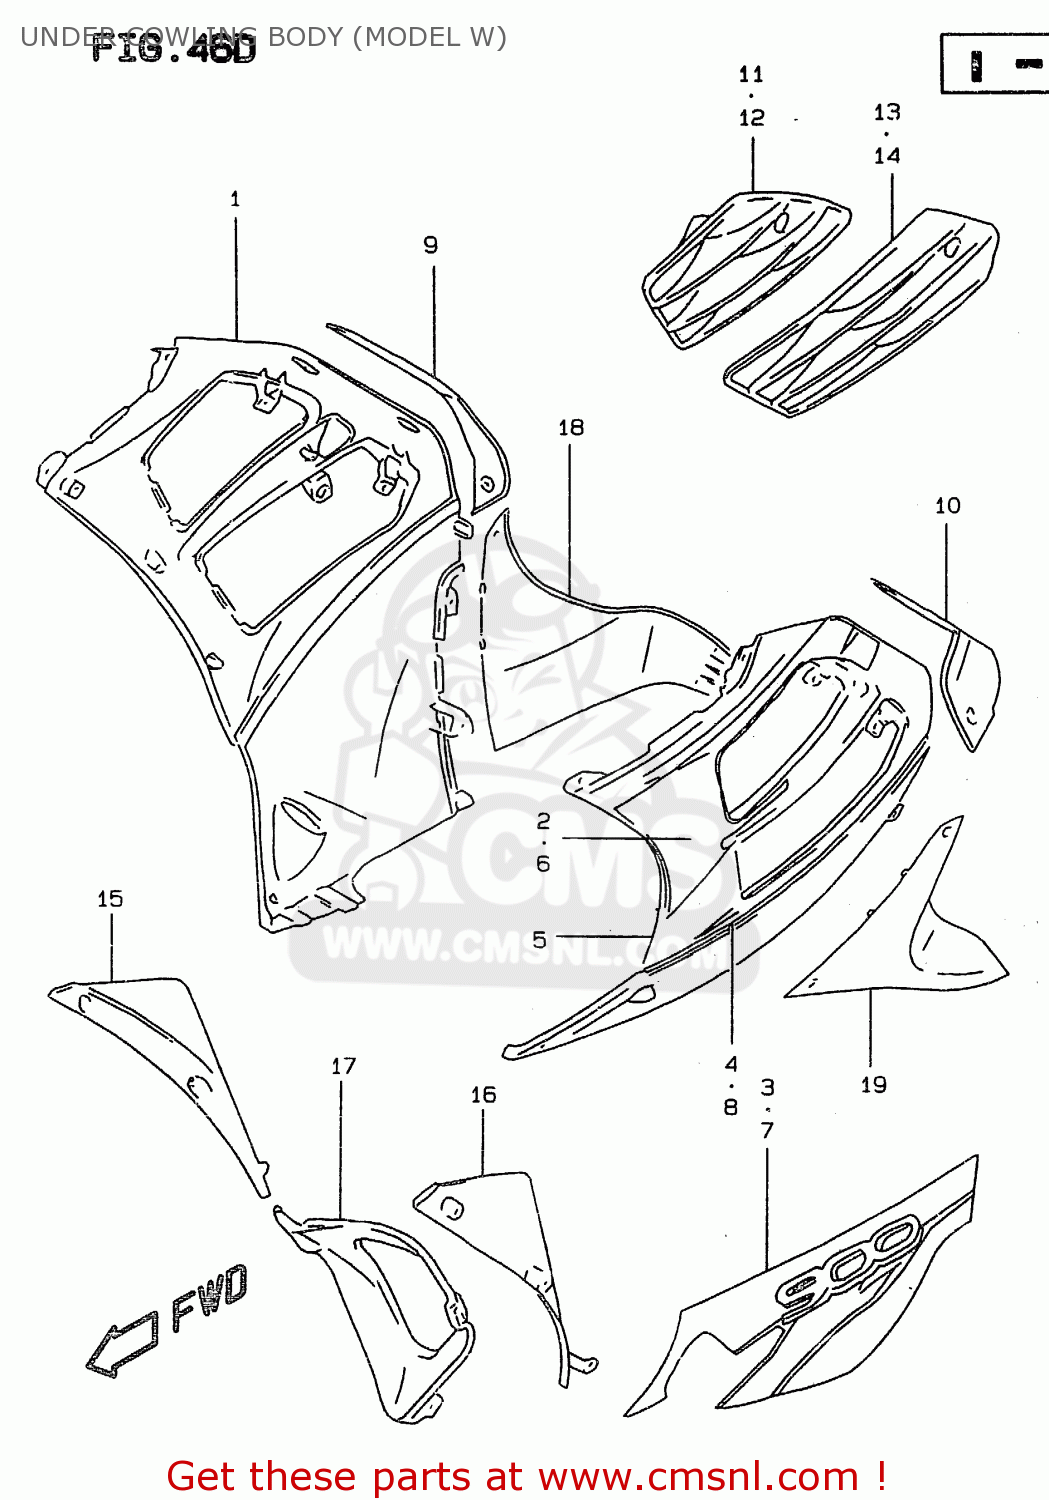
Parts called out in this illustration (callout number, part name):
1	COWLING ASSY,UNDER,R
2	TAPE SET, UNDER RH
3	TAPE SET,COWL UNDER LWR,R
4	TAPE,UNDER COWL,R
5	COWLING ASSY,UNDER,L
6	TAPE,COWL UNDER UPR,L
7	TAPE, LOWER LH
8	TAPE,UNDER COWL,L
9	PANEL,UNDER,R
10	PANEL,UNDER,L
11	COVER,UNDER COWL UPR,R
12	COVER,UNDER COWL UPR,L
13	COVER,UNDER COWL LWR,R
14	COVER,UNDER COWL LWR,L
15	COWLING,UNDER INNER,R
16	COWLING,UNDER INNER,L
17	COWLING,UNDER CTR
18	COWLING,UNDER RR,R
19	COWLING,UNDER RR,L
